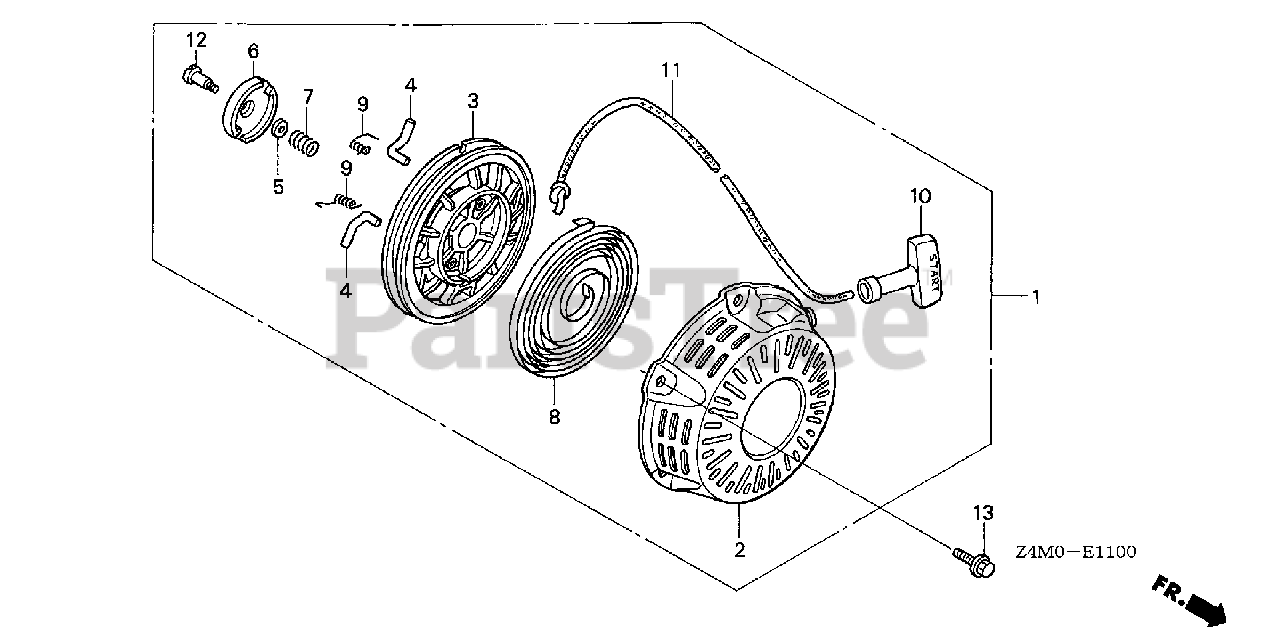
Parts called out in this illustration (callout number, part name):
1	STARTER ASSY., RECOIL *R280* (Honda Code 7546781). (POWER RED)
1	STARTER ASSY., RECOIL *NH1* (Honda Code 7552367). (BLACK)
2	CASE, RECOIL STARTER *R280* (Honda Code 7346836). (POWER RED)
2	CASE, RECOIL STARTER *NH1* (Honda Code 4193058). (BLACK)
3	REEL, RECOIL STARTER
4	RATCHET, STARTER
5	PLATE, FRICTION
6	GUIDE, RATCHET
7	SPRING, FRICTION
8	SPRING, RECOIL STARTER
9	SPRING, RETURN
10	KNOB, RECOIL STARTER
11	ROPE, RECOIL STARTER (#5X55")
12	SCREW, SETTING
13	BOLT, FLANGE (6X10)
